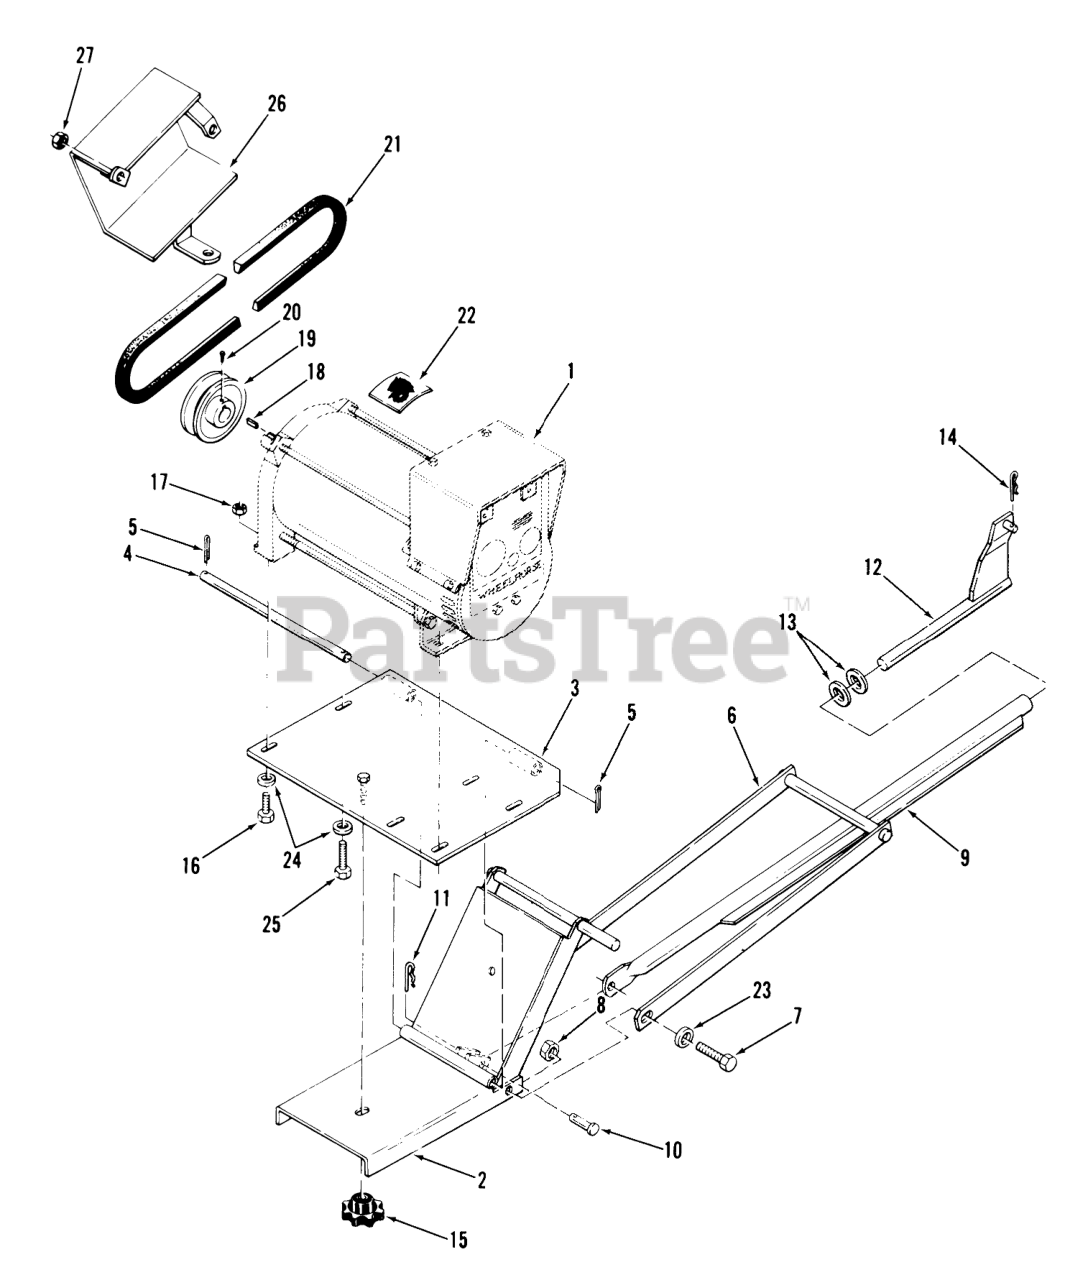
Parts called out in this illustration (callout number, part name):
1	Alternator 3000 Watt (Generac No. 6509-0)
1	Alternator 5000 Watt (Generac No. 6511-1)
2	Front Hitch
3	Mounting Plate
4	Pivot Rod
5	Cotter Pin
6	Mid Hitch
7	Bolt
8	Nut
9	Lift Tube
10	Clevis Pin 5/16 x 1 1/4
11	Hairpin Cotter
12	Lift Rod
13	Washer
14	Hairpin
15	Knob
16	Bolt
17	Nut
18	KEY-STRAIGHT
19	Pulley
21	Drive Belt
22	DECAL-LOGO
23	Washer
24	WASHER 5/16 SAE
25	Bolt
26	Belt Guard
27	Nut
